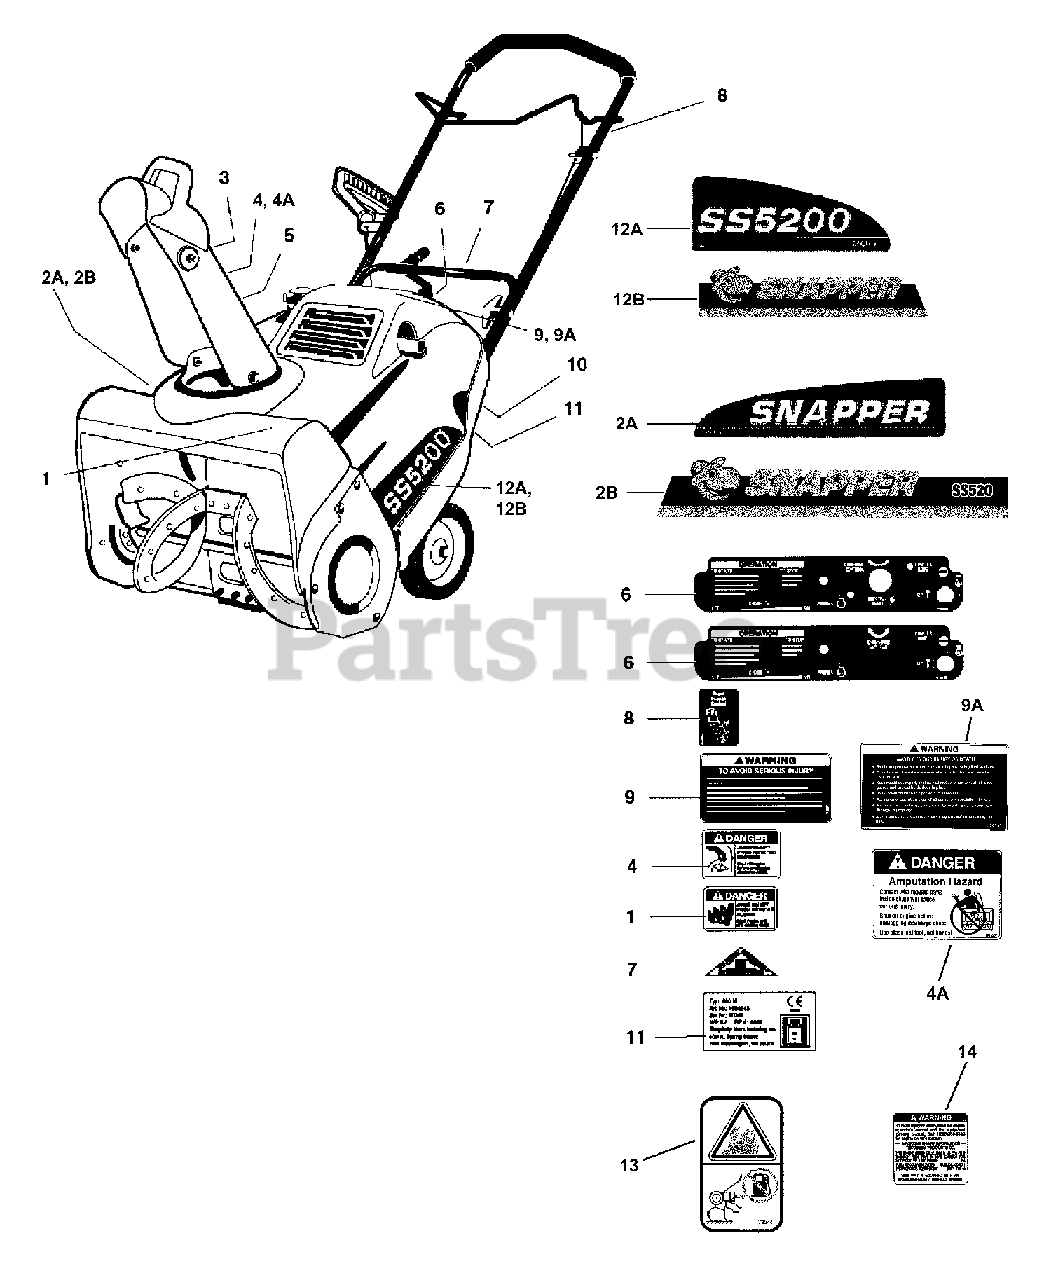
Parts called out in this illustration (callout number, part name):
1	DECAL, Danger, Auger
2A	DECAL, 5200 Logo, Right Hand (Snapper)
2B	DECAL, Top Cover RH (Snapper)
4	DECAL, Danger, Discharge Chute
4A	DECAL, Danger, Chute/Deflector
6	DECAL, Console (electric start models)
6	DECAL, Console (manual start models)
7	DECAL, OPEI
8	DECAL, Auger Control
9	DECAL, Warning
9A	DECAL, Warning, Safety Instructions
10	DECAL, Compliance
11	DECAL, Serial Number
12A	DECAL, 5200 Logo, Left Hand (Snapper)
12B	DECAL, Top Cover LH (Snapper)
13	DECAL, Fuel Safety
14	DECAL, Tec. 5HP Carb/EPA Certified
